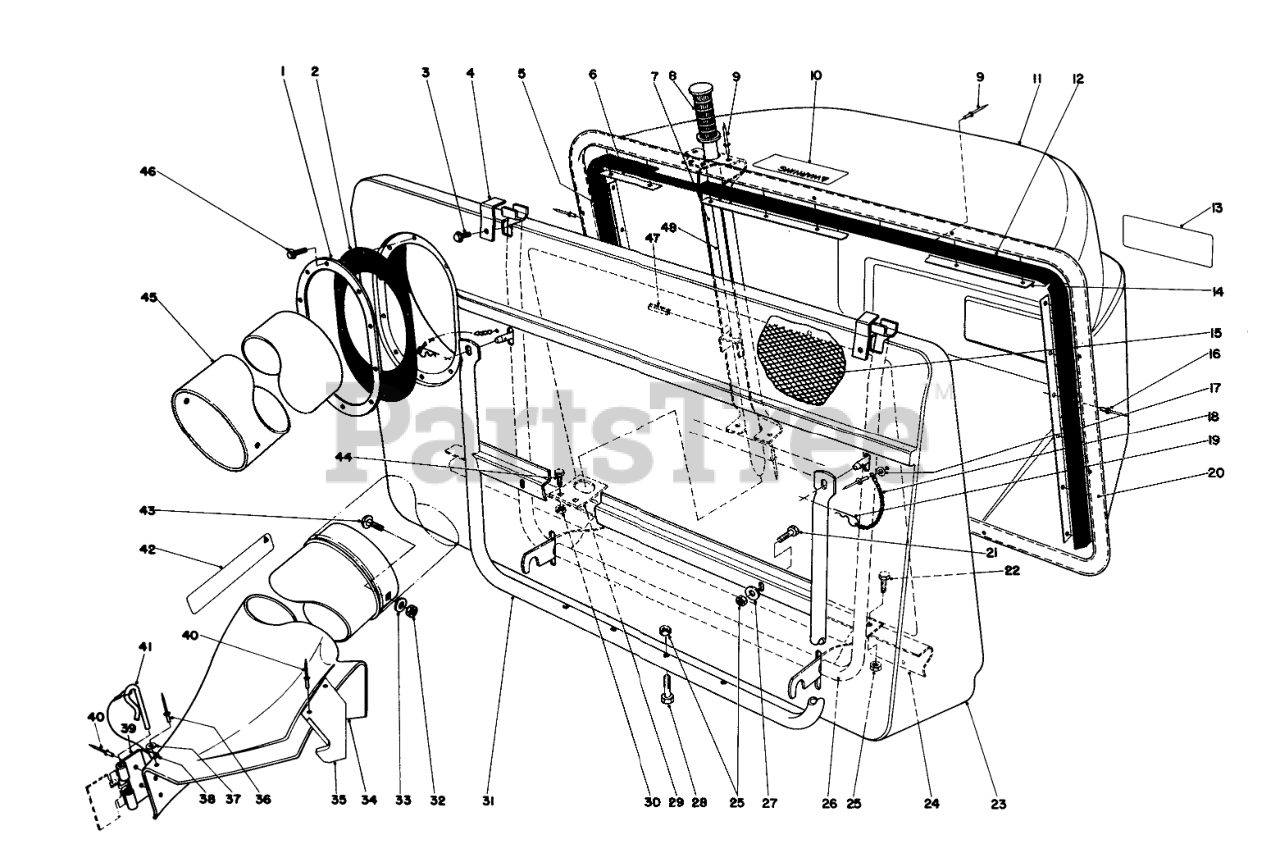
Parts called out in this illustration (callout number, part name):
1	RING-RETAINING
2	RING-RETAINER, RUBBER
3	SCREW-HWH
4	RETNR PIVOT BRKT
5	RH BAG SEAL
6	RETNR TOP EXT.
7	DUMP HDLE CHANL WA
10	DECAL
11	REAR GRASS BASKET
12	Seal-Bag LH.
13	EASY EMPTY BAG DECAL
14	BAG RETNR EXT.
15	Screen Bag
17	WASHER
18	10 LINK CHAIN W/O HOOK
19	PIN-HAIR
20	BAG SUPT ASM FRM
21	SCREW-HH
22	SCREW-HH
23	Bag Front
24	FRAME SUPT BRKT B
25	NUT-LOCK, CONE
26	Bag Frame
27	WASHER-PLAIN
28	SCREW-HH
29	Hanger-Frame Lower
30	NUT-LOCK, CONE
31	BAG SUPPORT WA
32	NUT-KEPS
33	WASHER-FLAT
34	Chute Assembly (Incl. Ref. #36-43)
35	CHUTE SUPT BRKT
36	RIVET-BLIND
37	WASHER-PLAIN
38	LANYARD
39	BRACKET-MOUNTING, CHUTE
40	RIVET-BLIND
41	PIN-LOCKING, CHUTE
42	Decal-Chute
43	Bolt-Carriage
44	SCREW-HH
45	Duct
46	SCREW-HWHTF
47	PIN-ROLL
48	DUMP HANDLE ASM
